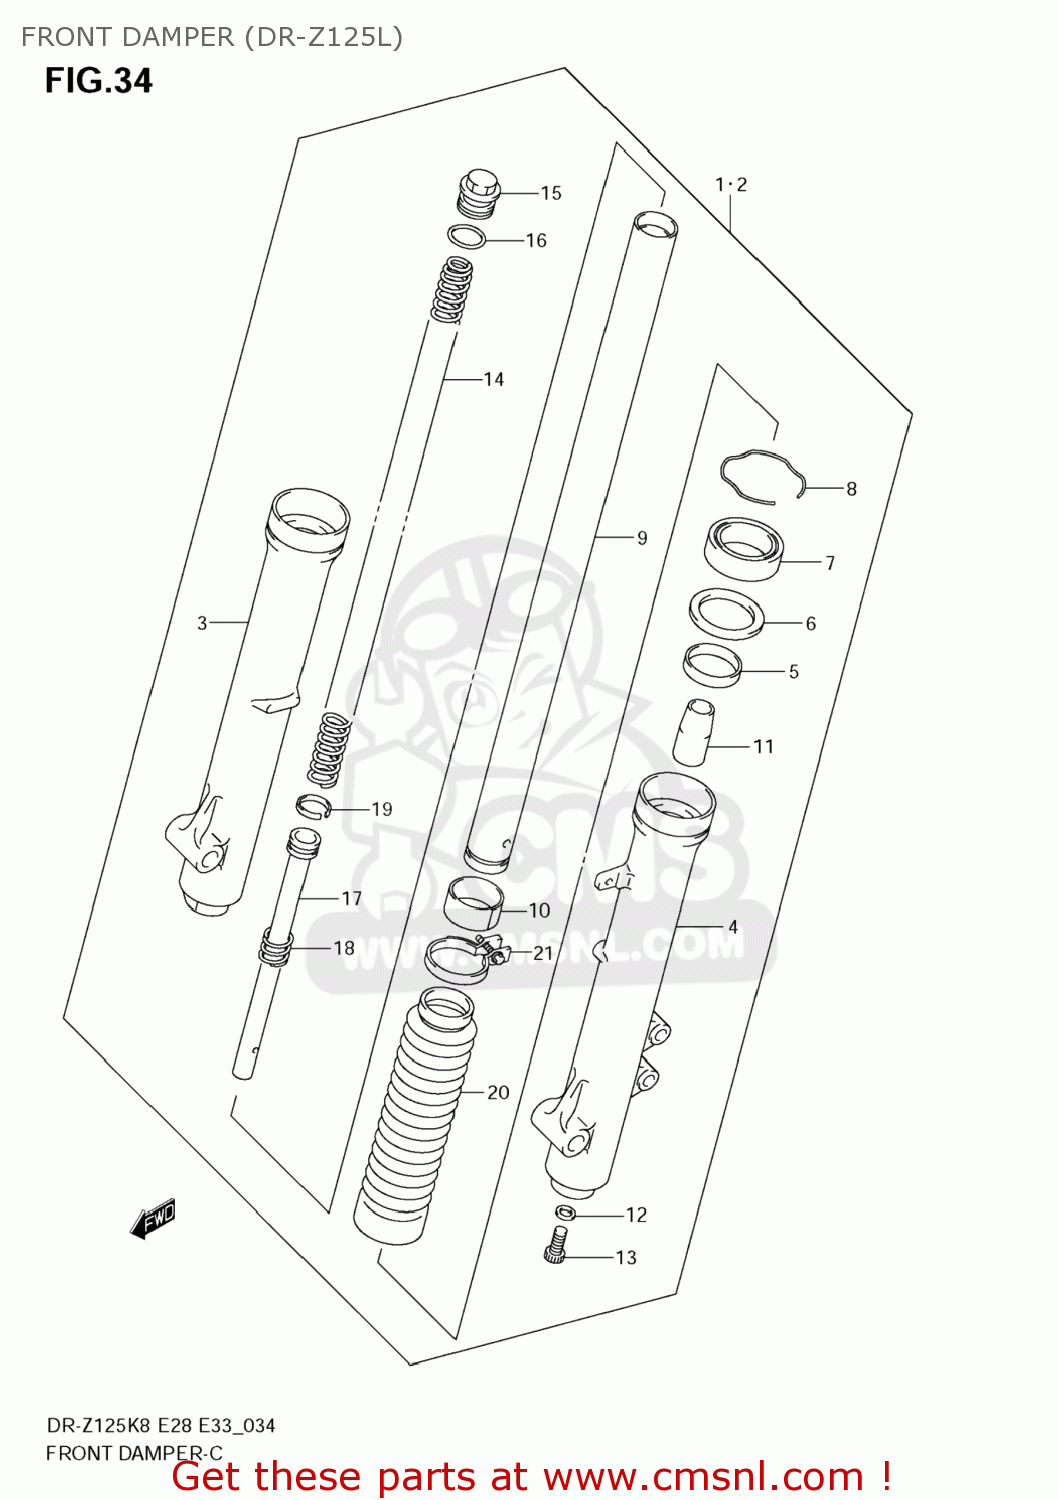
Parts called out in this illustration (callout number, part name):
1	DAMPER ASSY,FR FORK,R
2	DAMPER ASSY,FR FORK,L
3	TUBE,OUTER,R
4	TUBE,OUTER,L
5	BUSH,GUIDE
6	SPACER,SEAL
7	SEAL,OIL
8	SEAL,OIL STOPPER RING
9	TUBE,INNER
10	BUSH,SLIDE
11	PIECE,OIL LOCK
12	GASKET (NAS)
13	BOLT(8X27)
14	SPRING,FR
15	BOLT
16	O RING
17	CYLINDER
18	SPRING,REBOUND
19	RING
20	BOOT
21	BAND
